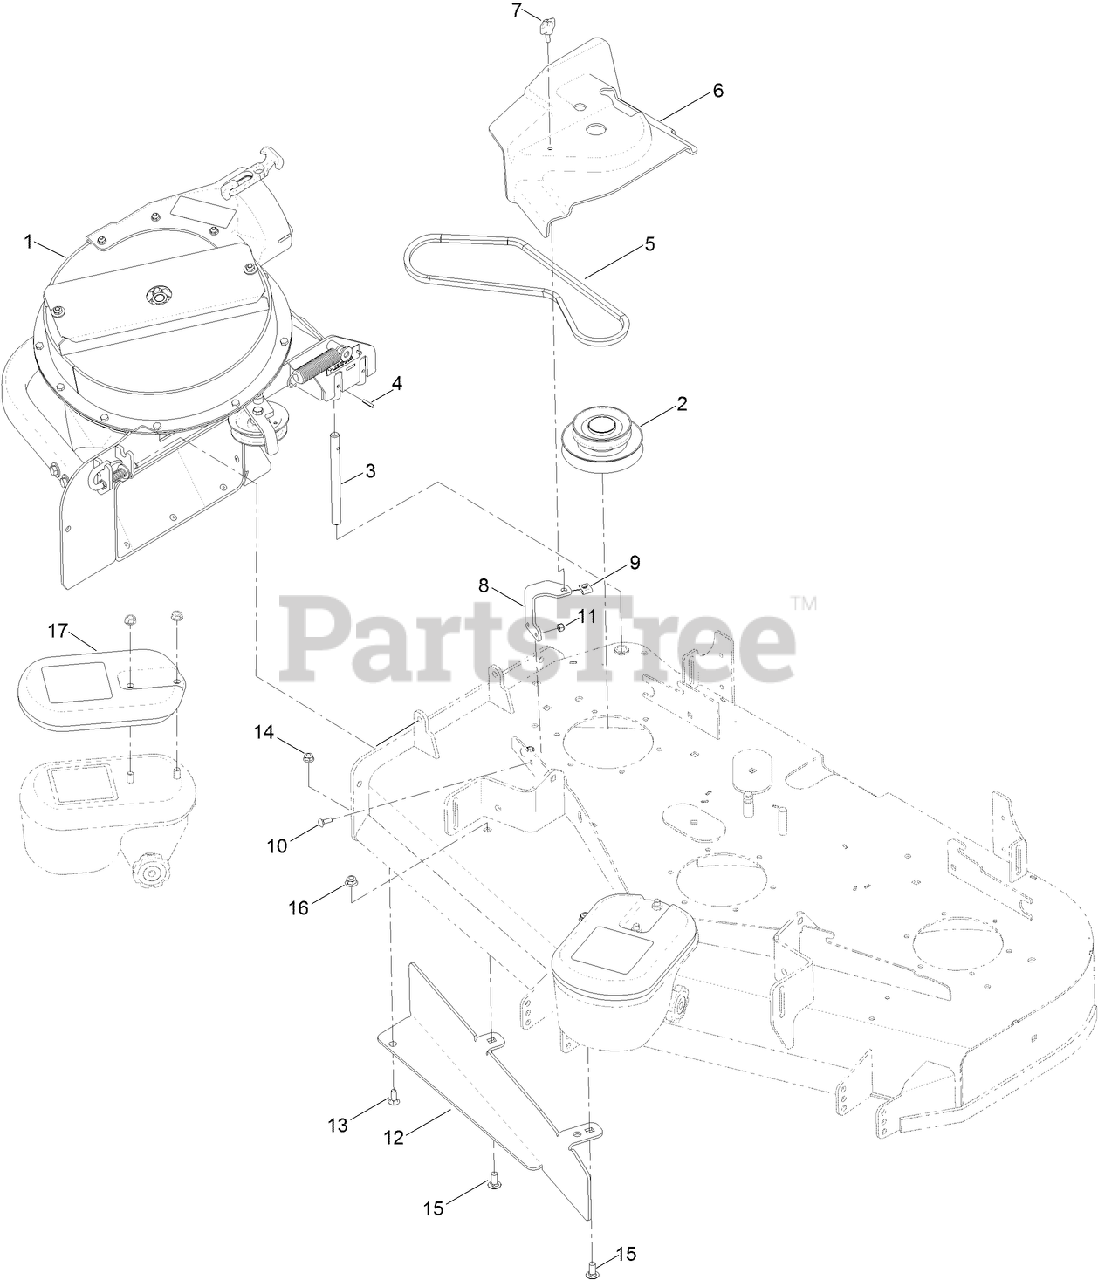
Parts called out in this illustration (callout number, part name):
1	BLOWER ASM
2	DRIVE-JACKSHAFT
3	SHAFT-CATCHER, GRASS
4	PIN-ROLL
5	Belt-V
6	COVER-BELT
8	BRACKET-COVER, BELT
9	NUT-SPEED
10	BOLT-CARR
11	NUT-LOCK, NI
12	BAFFLE-BAGGER
13	SCREW-CARR
14	NUT-HF, NI
15	SCREW-CARR
16	NUT-HF, NI
17	WEIGHT
